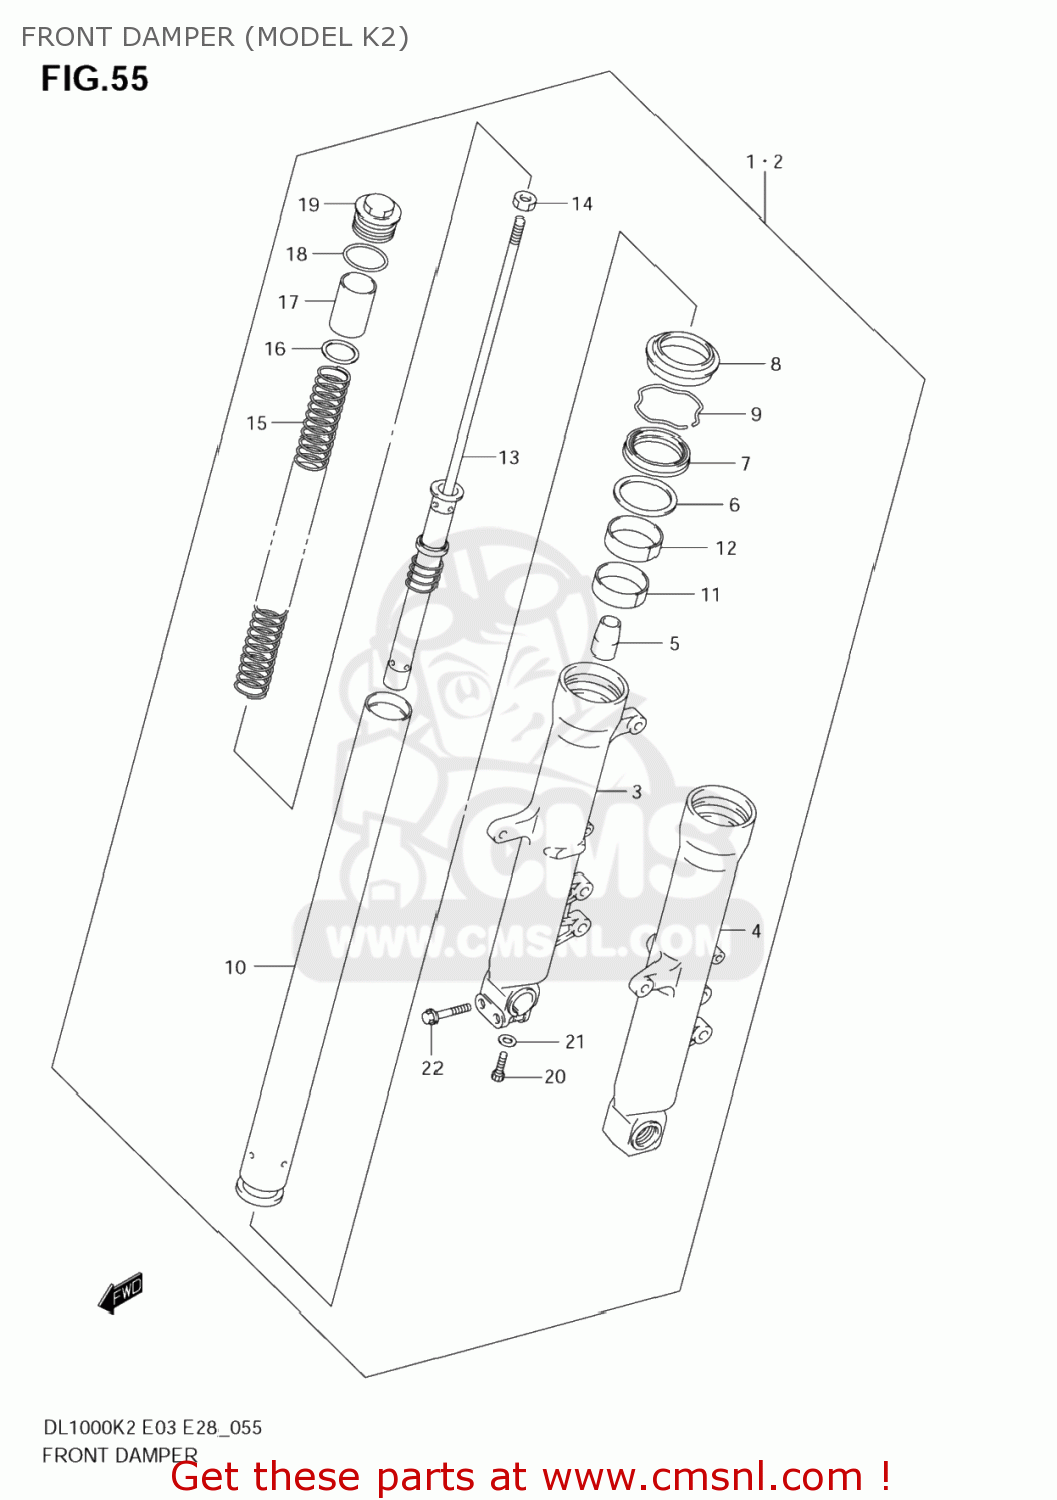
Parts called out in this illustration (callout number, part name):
1	DAMPER ASSY,FR FORK,R
2	DAMPER ASSY,FR FORK,L
3	TUBE,OUTER,R
4	TUBE,OUTER,L
5	PIECE,OIL LOCK
6	SPACER,SEAL
7	SEAL,OIL
8	SEAL,DUST
9	CIRCLIP,FORK OIL SEAL
10	TUBE,INNER
11	BUSH,SLIDE
12	BUSH,GUIDE
13	ROD,FR DAMPER
14	NUT
15	SPRING,FR
16	SEAT,SPRING LWR
17	COLLAR,SPRING(32.9X34X50)
18	O RING
19	BOLT,FORK
20	BOLT(8X27)
21	GASKET (NAS)
22	BOLT
